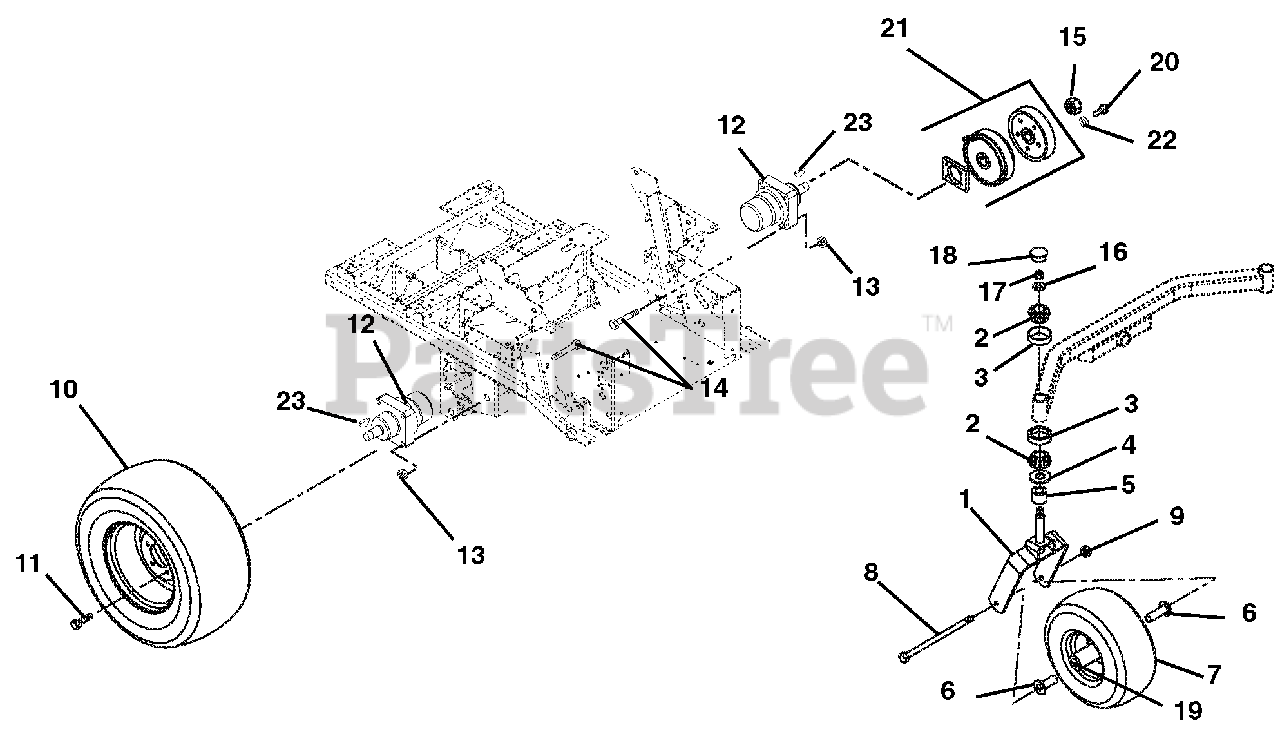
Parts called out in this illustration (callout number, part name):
1	Fork, Front
2	Bearing, Cone w/ Grease
3	Bearing, Cup 1.980 x .420
4	Bearing Seal 1.5 x 2 x .18
5	Spacer, PM, 1.03 I.D. x 1.5 O.D. x .375
6	Spacer, Wheel
7	Wheel/Tire Assembly 15 x 6-6
8	Bolt, Hex .50-13 x 9.00 Grade 5
9	Nut, Locking Center .50-13
10	Tire/Wheel Assembly 24 x 11.50-12
11	Bolt, Lug .50-20 x 1.38
12	Hydraulic Wheel Motor (Includes item 15) (Pg 20)
13	Nut, Locking Top Flange .50-13
14	Bolt, Wheel Motor .50-13 x 2.75
15	Nut , Lock Jam Patch (Included with 12)
16	Washer, Flat Steel 812 x 1.50 x .135
17	Nut, Jam Center-Lock .75-16
18	Cap, Dust
19	Bearing, 25mm I.D. x 52mm OD x 15mm
20	Bolt, Hex .31-18 x 1.5 Grade 8 EP30
21	Kit, Parking Brake Service
22	Washer, Locking .31 x .078 Regular
23	Key, Woodruff .31 x 1.00 (For Service Only)
